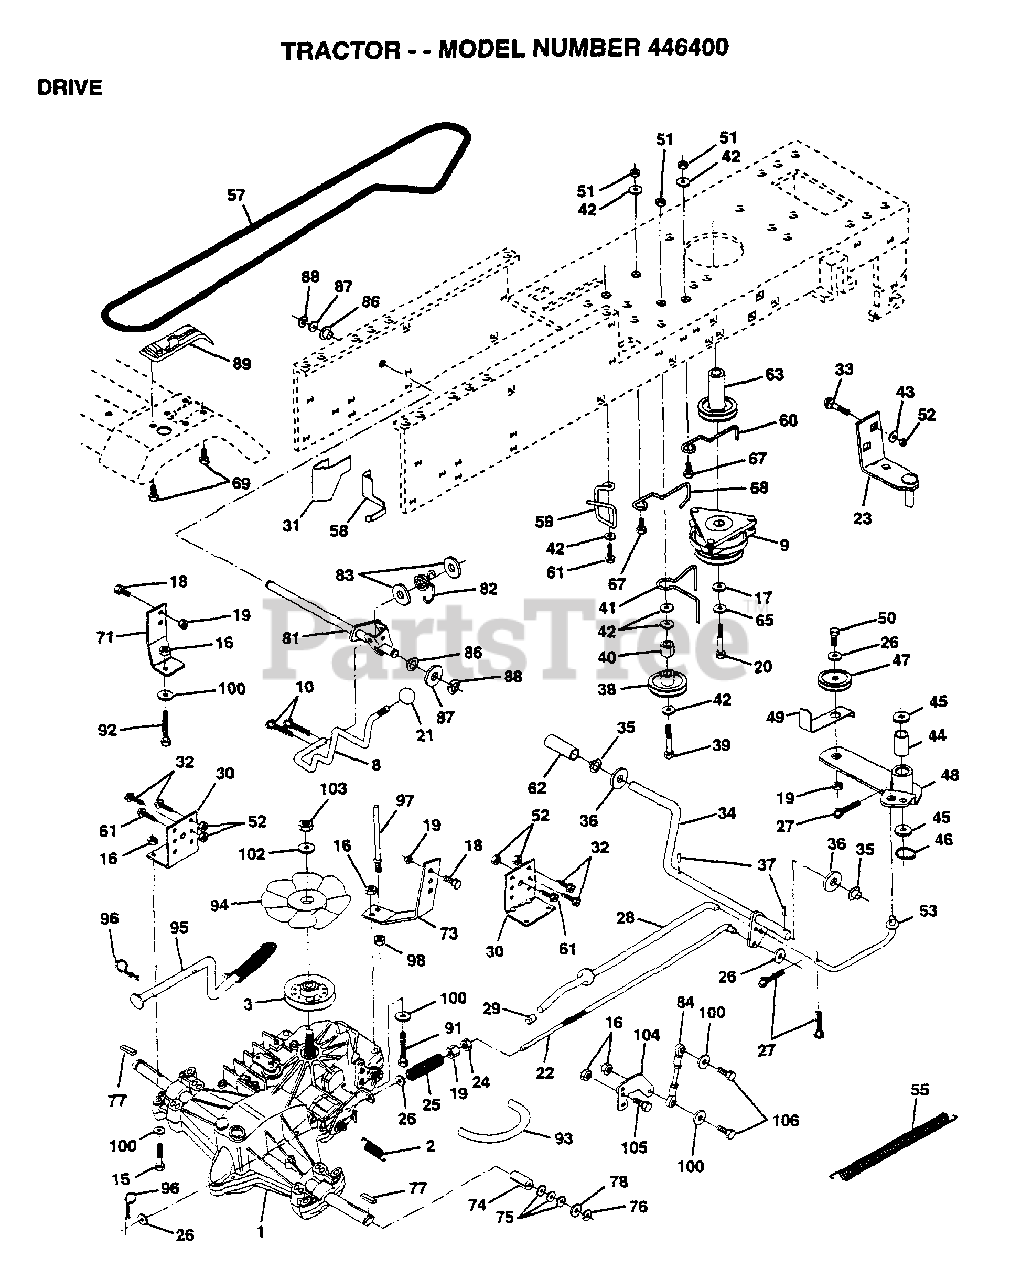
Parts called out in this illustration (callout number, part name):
2	SPRING RET BRAKE
3	PULLEY.TRANSAXLE
8	ROD SHIFT FEND YT
10	PIN COTTER 1/8
15	BOLT HEX
16	NUT
17	WASHER
18	BOLT
19	NUT
21	KNOB.DUCKHEAD.1/2
22	ROD.BRAKE.HYDRO.
23	BRACKET.ASM.MTG
24	NUT
25	SPRING ROD LT
26	WASHER
27	COTTER PIN
28	ROD.BRAKE.PARK.LT
29	PLUNGER CAP T
30	TRANSAXLE MTG BKT
31	"KEEPER,BELT LH T"
32	BOLT
33	BOLT
35	NYLON BEARING
36	WASHER LT
38	PULLEY.IDLER.FLAT
39	BOLT
40	SPACER T
41	BELT KEEPER LT
42	WASHER
43	WASHER T
44	"LY, BEARING"
45	WASHER LT
46	KLIP RING
48	ARM IDLER
49	RETAIN BELT
53	"LINK, CLUTCH T"
55	"SPRING, RETURN LT"
57	"BELT.GD DRV 82"""
58	KEEPER BELT LH
59	KEEPER BELT CNTSP
60	KEEPER BELT ENGLH
61	SCREW
62	PEDAL COVER T
63	PULLEY CLU ELEC
65	LOCKWASHER
67	BOLT
68	"KEEPER,BLT ENG LT"
69	SCREW HEXWSH H-L
71	STRAP TORQ LH HYD
73	STRAP TORQ RH HYD
74	SPACER SPLIT
75	WASHER
76	E-RING LT
77	SQUARE KEY
78	WASHER
82	"SPRING,TORSION"
83	WASHER
84	ROD.TIE.BALL.4.75
86	BUSHING
87	WASHER D
88	KLIP RING
92	HEX BOLT
93	"LINE FUEL HYD 4"""
94	"FAN 7"" HYDRO"
96	RETAINER M
97	BOLT KEEPER RH
98	NUT
100	WASHER M
102	WASHER BELLEVILLE
103	NUT NYLON 1/2-20
104	ARM CONTROL HYDRO
105	SCREW CAP 5/16-18
106	BOLT
